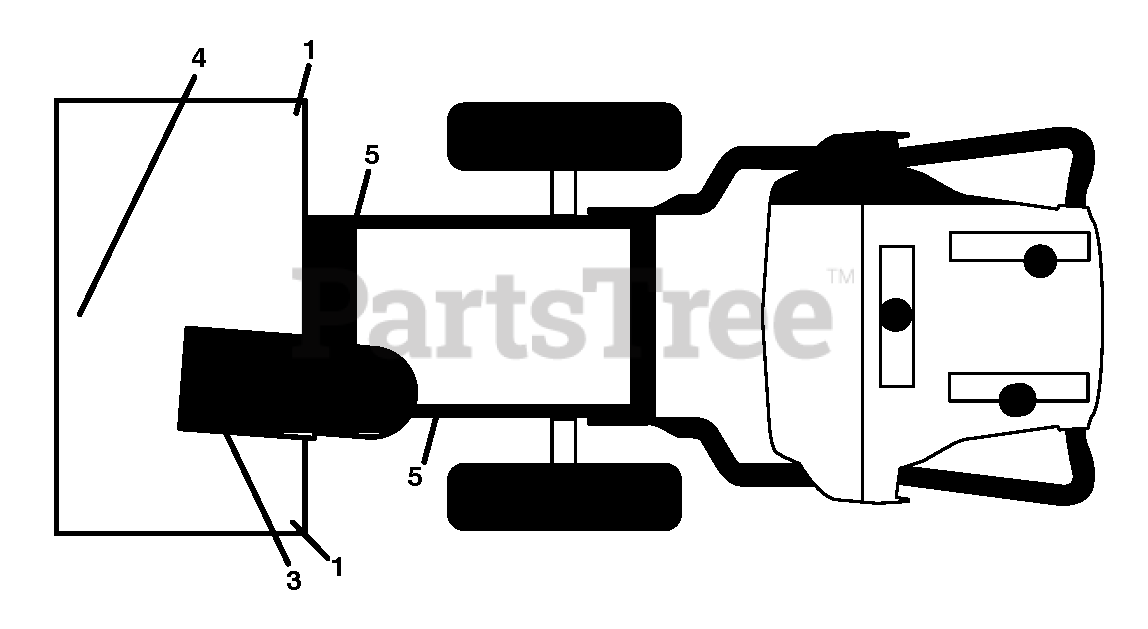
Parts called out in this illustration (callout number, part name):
1	DECAL.AUGER.SAFETY.
3	DECAL.CHUTE.SAFETY.EU/SC.17
4	DECAL.AUGER."
5	DECAL.BELT.GUARD.
